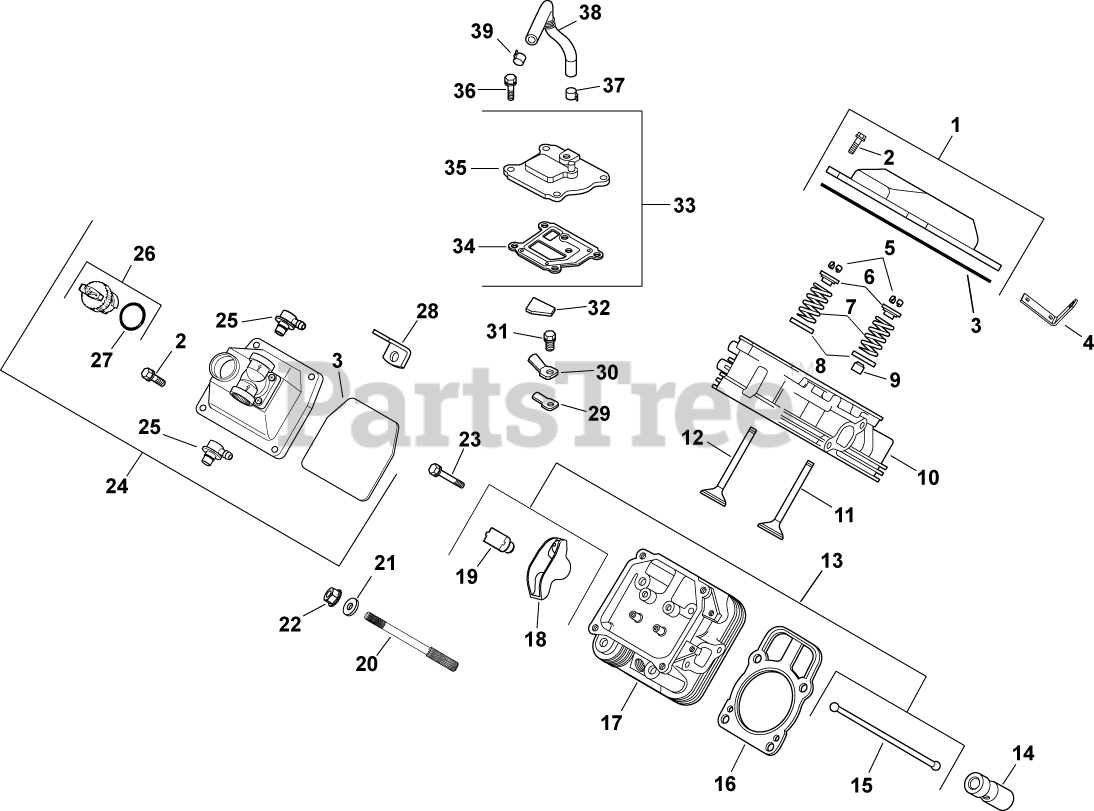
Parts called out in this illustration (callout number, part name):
1	KIT, VALVE COVER-PLAIN
2	SCREW, FLG M6X1.0X30
3	O-RING (YELLOW), VALVE COVER
4	STRAP, LIFTING-USE 25 445 03-S
5	KIT, RETAINER
6	RETAINER, VALVE SPRING - USE 25 173 28-S
7	SPRING, VALVE
8	RETAINER, SPRING
9	SEAL, VALVE STEM - (#2503214S)
10	HEAD, SERVICE ASSY CYL #1-USE 24 318 106
11	VALVE, INTAKE (STD)
12	VALVE, EXHAUST (STD) - USE 32 016 01-S
13	KIT, VALVE TRAIN
14	LIFTER, HYDRAULIC VALVE-USE 25 351 10-S
15	ROD, PUSH
16	CYL HEAD GASKET KIT-USE 24 841 04-S
17	HEAD, SERVICE ASSY CYL #2-USE 24 318 114
18	ARM, ROCKER
19	PIVOT, ROCKER ARM
20	STUD, M8X1.25
21	WASHER, FLAT 8.6 MM
22	NUT, FLG M8X1.25
23	SCREW, FLG M6X1.0X34
24	KIT, VALVE COVER-FUEL PUMP
25	KIT, 90 DEG. FITTING
26	CAP ASSY, OIL FILL (YELLOW)
27	O-RING-USE 24 153 32-S
29	REED, BREATHER
30	RETAINER, REED
31	SCREW, FLG THD FRM M5X.8X10
32	FILTER, BREATHER
33	KIT, BREATHER ASSEMBLY
34	GASKET, BREATHER-USE 24 041 67-S
35	COVER, BREATHER -USE 24 033 01-S
36	SCREW,FLG THD FRM M6X1.0X20-(#25086396S)
37	CLAMP, HOSE (KM)-USE 25 237 31-S
38	HOSE, BREATHER
39	CLAMP, BAND SPRING HOSE-(#2523737S)
2401602-S	VALVE, EXHAUST (.25)
2401702-S	VALVE, INTAKE (.25)
2404101-S	GASKET, INTAKE MANIFOLD USE 24 041 79-S
2404149-S	GASKET, EXHAUST
2415327-S	O-RING, INTAKE PORT
2507204-S	STUD, EXHAUST (KM)-USE 25 072 24-S
2514106-S	TOOL, INSTALLATION (SNAP RING)
2535714-S	Lubricant, Camshaft/Lifter (0.25 oz.)
24755147-S	KIT, CYLINDER HEAD HARDWARE
